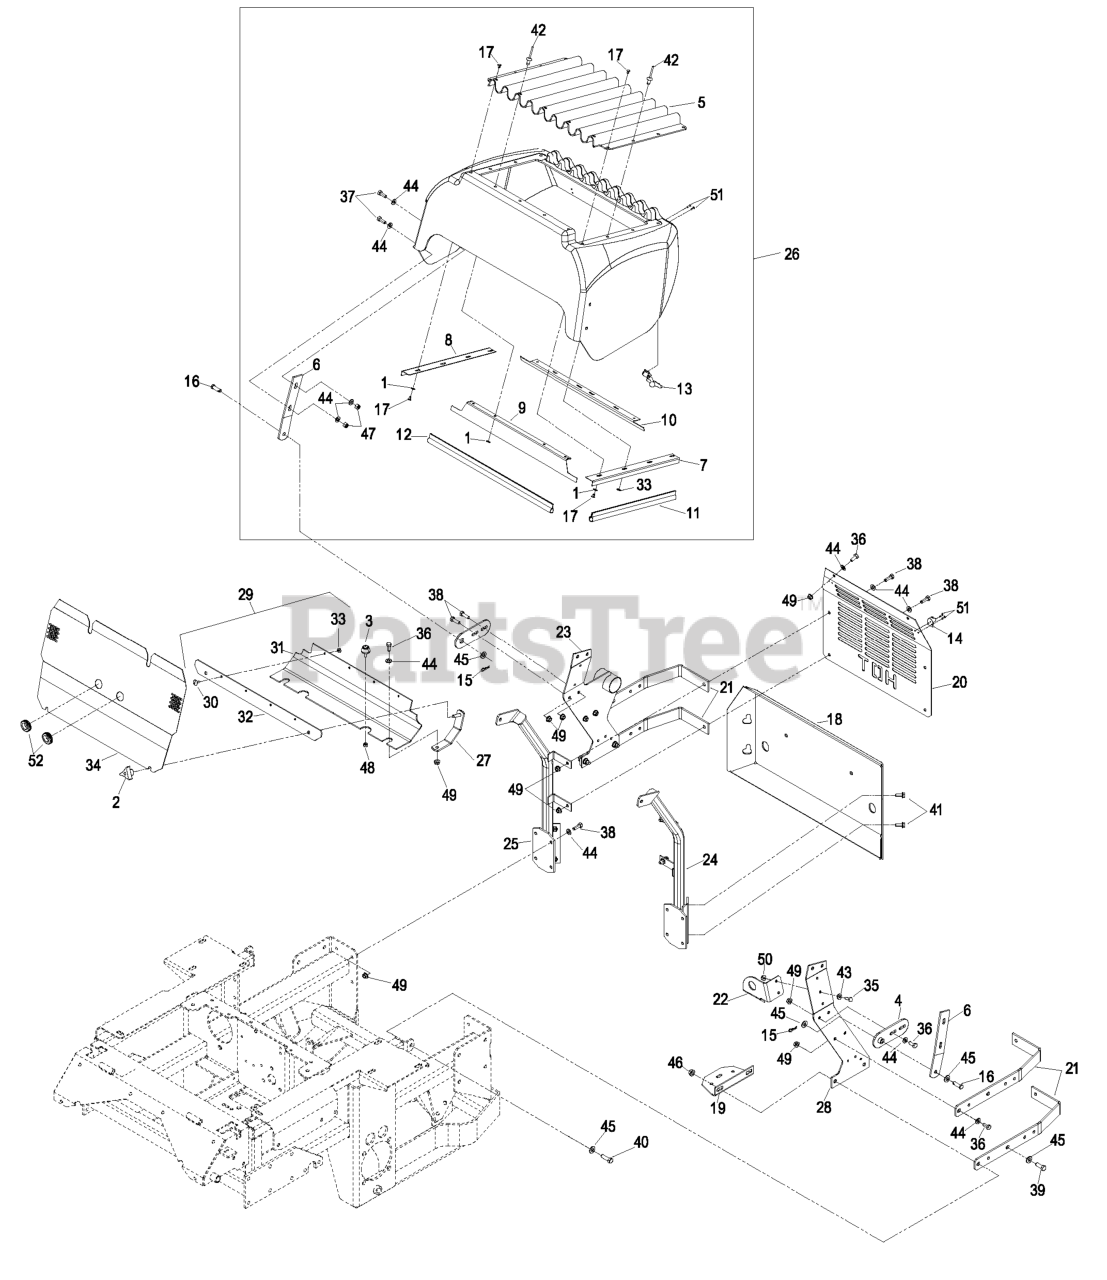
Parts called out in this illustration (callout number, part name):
1	WASHER-SPRING
2	KNOB-3 PRONG
4	SHACKLE-HINGE
5	SCREEN-RADIATOR
6	PLATE-HINGE, HOOD
7	ANGLE-RADIATOR, LH
8	ANGLE-RADIATOR, RH
9	ANGLE-RADIATOR, TOP
10	ANGLE-RADIATOR, BOTTOM
11	SEAL-TRIM
12	SEAL-TRIM
13	LATCH-RUBBER
15	PIN-COTTER
16	PIN-CLEVIS
18	WLD,REAR BUMPER
19	Bracket, Bottle
20	GUARD-MUFFLER
22	BRACKET-BUZZER
23	RH RADIATOR AND AC SUPPOR
24	FRAME-UPPER, LH REAR
25	FRAME-UPPER, RH REAR
26	KIT,XP HOOD
27	MOUNT-BELT SHIELD, ENGINE
28	MOUNT-SIDE, LH
30	RIVET-POP
32	Strip, Belt Shield
33	WASHER-FLAT
35	SCREW-HH
36	SCREW-HH
37	SCREW-HH
38	SCREW-HH
39	SCREW-HH
40	SCREW-HH
41	SCREW-HHF
43	WASHER-FLAT
44	WASHER-PLAIN
45	WASHER-FLAT
46	NUT-HHF, WHIZ
47	NUT-LOCK, NI
48	NUT-LOCK, NI
52	GROMMET-RUBBER
